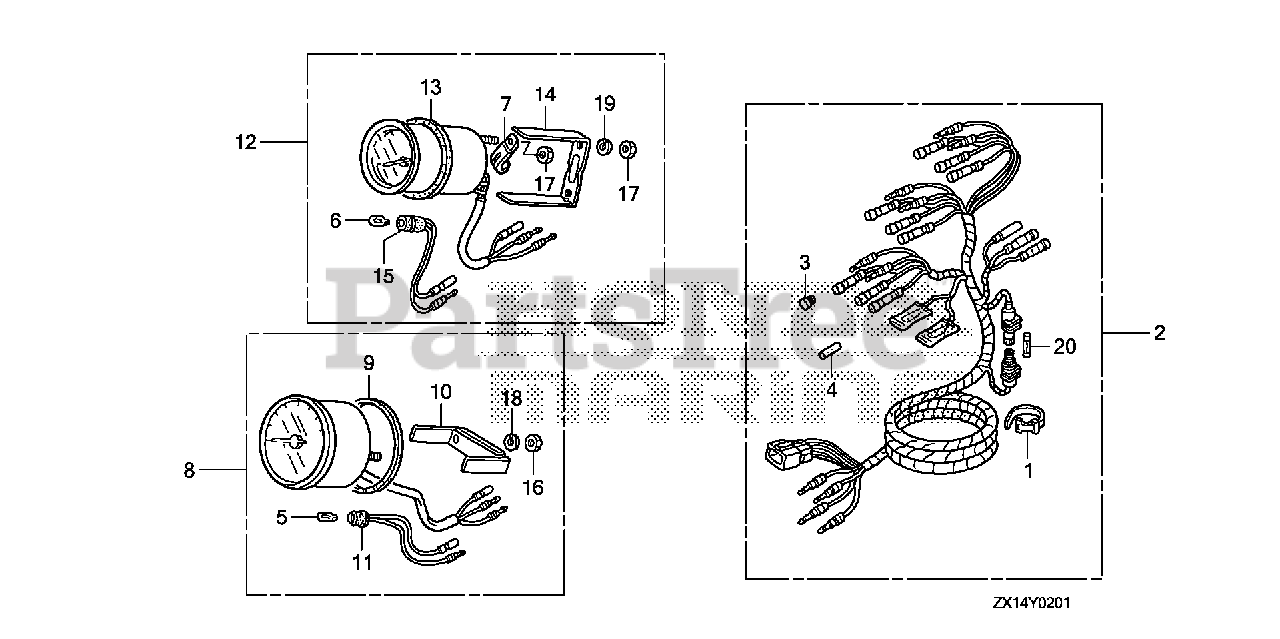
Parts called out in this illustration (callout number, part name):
1	BAND B1, WIRE
2	HARNESS ASSY., METER (A)
3	PLUG, CONNECTOR (INNER)
4	PLUG, CONNECTOR (OUTER)
5	BULB, WEDGE BASE (T10) (12V 1.7W) (STANLEY)
6	BULB, WEDGE BASE (12V 1.7W)
7	CLAMP
8	TACHOMETER ASSY.
9	GASKET
10	BRACKET
11	SOCKET
12	METER ASSY., TRIM
13	GASKET
14	BRACKET
15	SOCKET
16	NUT, HEX. (5MM)
17	NUT, HEX. (4MM)
18	WASHER, SPRING (5MM)
19	WASHER, SPRING (4MM)
20	FUSE A (10A)
